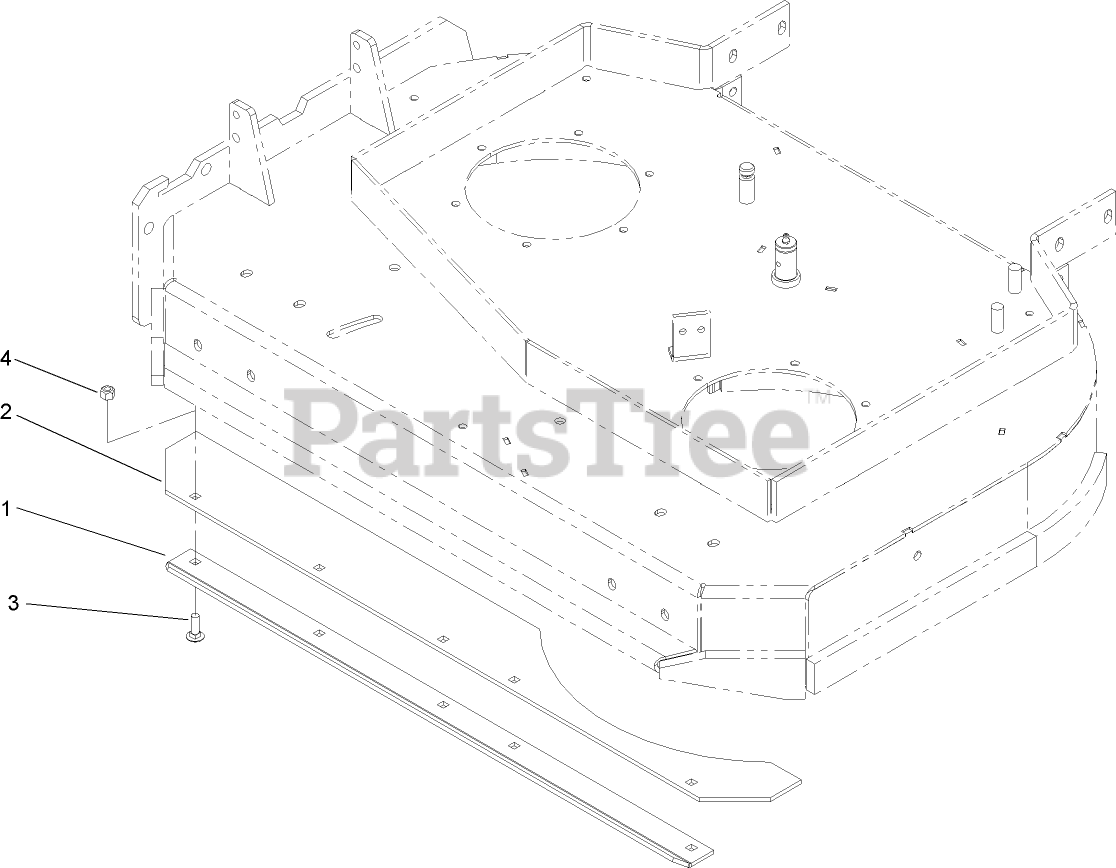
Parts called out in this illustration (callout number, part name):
1	SKID-SKIRT
2	SKIRT-RUBBER
3	BOLT-CARR
4	NUT-LOCK, NI
